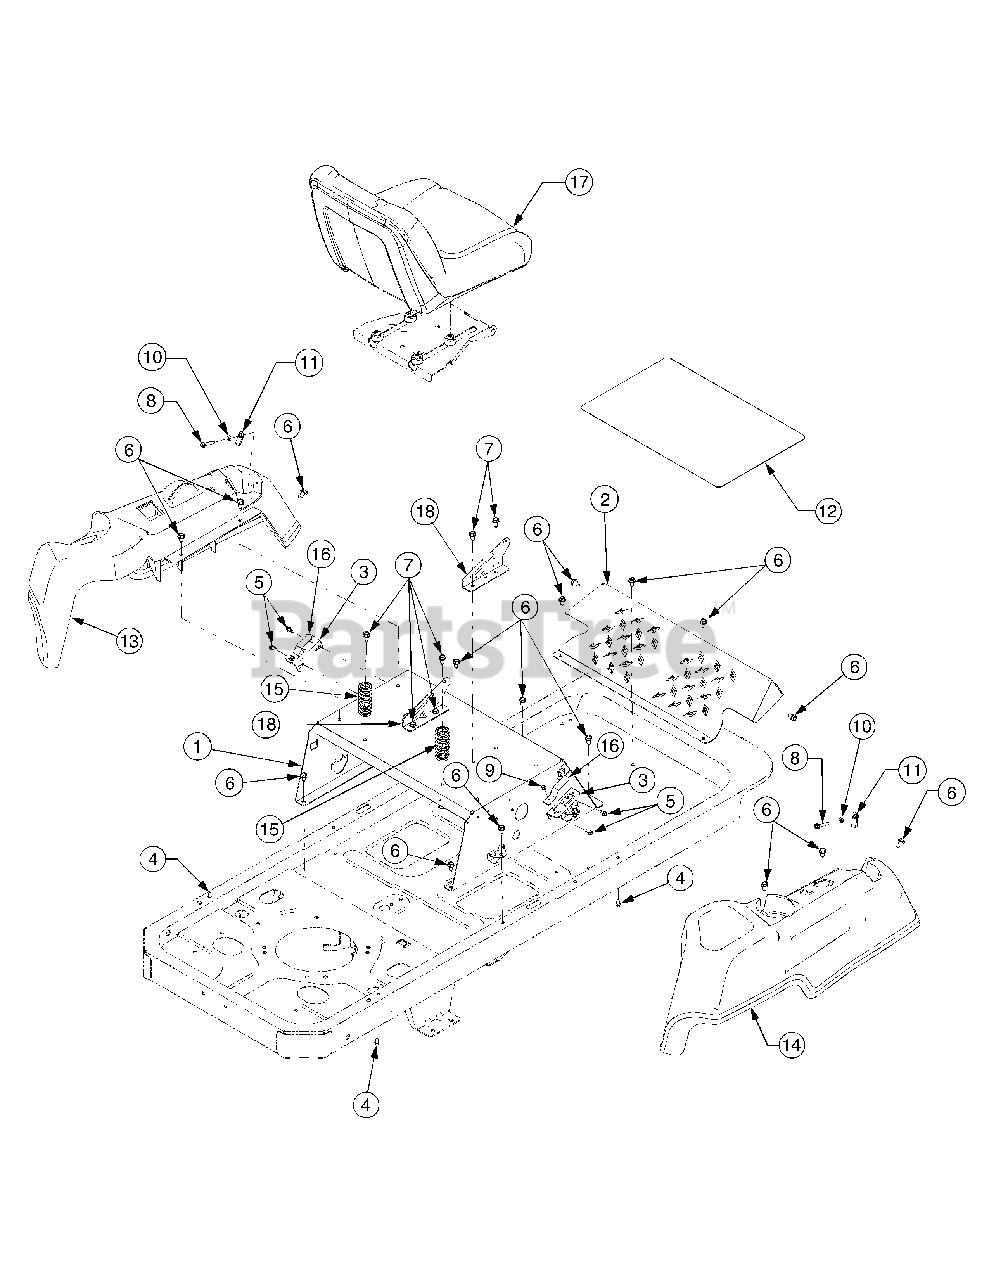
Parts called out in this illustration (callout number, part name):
1	Graphic, Warning
1	Graphic, Deck Height
4	Screw, Hex Wash. Hd Tapp, #12-16 x .50
5	Screw, Hex Wash. Hd. Tapp.1/4-20 x .5
6	Screw, Hex Wash. Hd. Tapp 5/16-18 x .625
7	Screw, Hex Wash. Hd. Tapp 5/16-12 x .75
8	Screw, Hex Wash. Hd. Tapp.1/4-20-x 1.5
9	Screw, Hex Wash. Hd Tapp #10-16 x .375
10	Nut, Hex Jam, 1/4-20 GR2
11	Nut, U Type Speed, 1/4-20
12	Pad, Abrasive Foot Plate
13	Console, LH
13	Graphic, Instruction
13	Graphic, Cub Cadet
13	Graphic, Throttle Control
14	Console, RH
14	Graphic, Instruction
14	Graphic, Cub Cadet
15	Spring, Compression, 1.28 x 3.125
16	Spring, Switch Actuator
17	Graphic, Cub Cadet/USA
